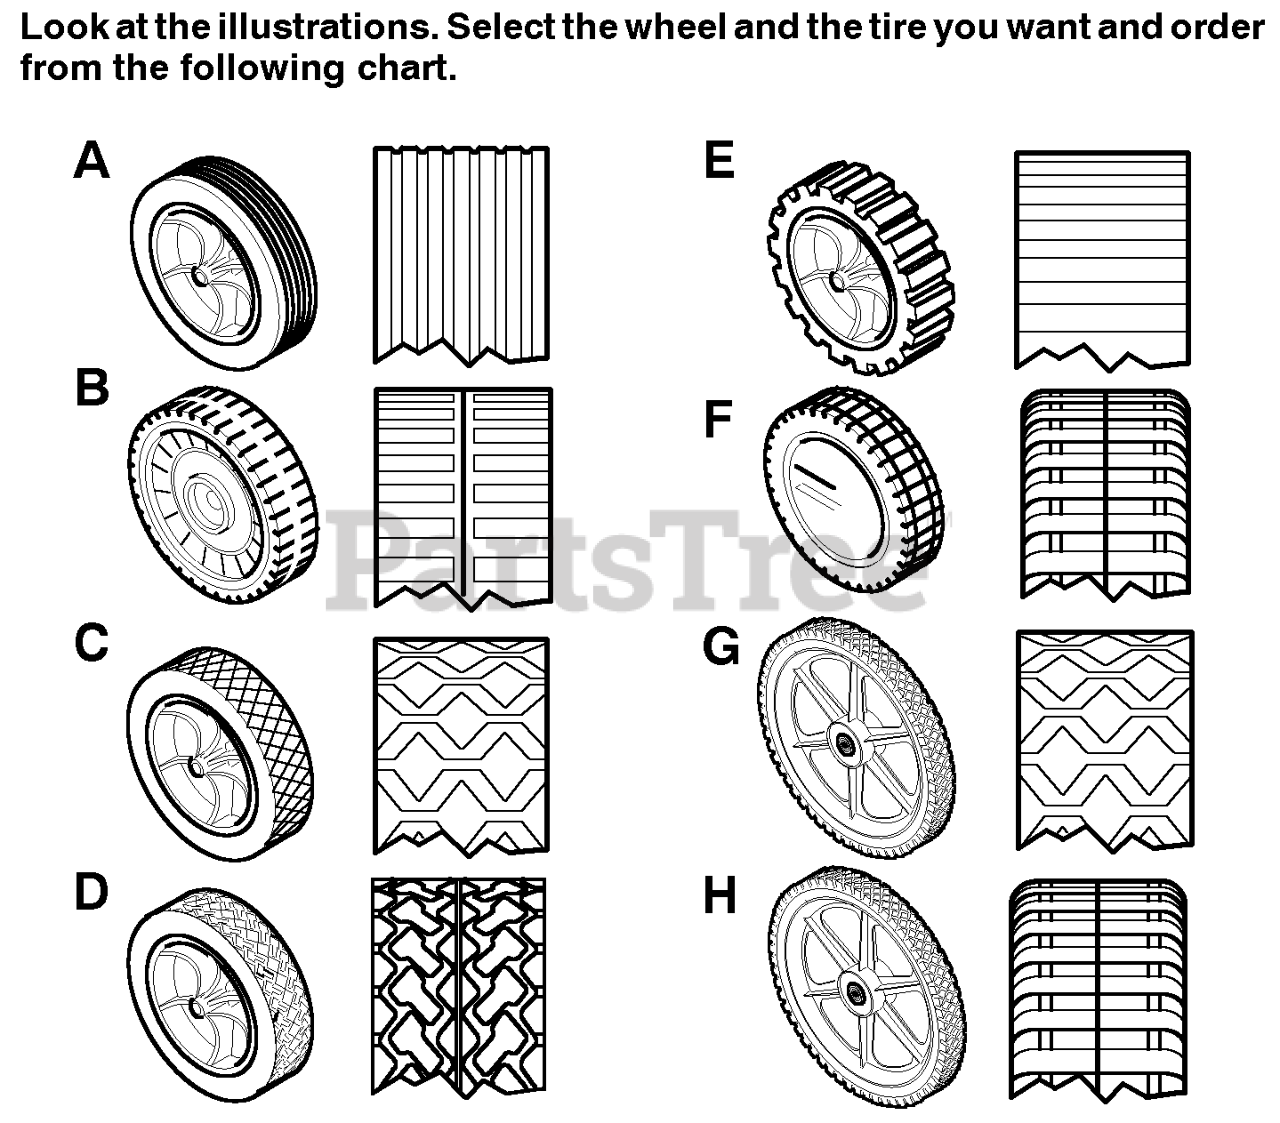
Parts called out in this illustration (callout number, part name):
A	WHEEL & TIRE ASSEMBLY, Light Gray, 8"
A	8-inch Plastic, Dark Gray
A	8-inch Metal, White
B	7-inch Plastic, White
B	7-inch Plastic, Light Gray
B	7-inch Plastic, Dark Gray
C	6-inch Plastic, White
C	7-inch Plastic, White
C	7-inch Plastic, Light Gray
C	7-inch Plastic, Dark Gray
C	8-inch Plastic, White
C	8-inch Plastic, Light Gray
C	8-inch Plastic, Dark Gray
C	8-inch Metal, White
D	7-inch Plastic, White
D	WHEEL & TIRE ASSEMBLY, White, 8"
D	8-inch Plastic, Light Gray
D	8-inch Plastic, Dark Gray
E	WHEEL & TIRE ASSEMBLY, White, 8"
E	8-inch Plastic, Dark Gray
E	8-inch Metal, White
F	WHEEL & TIRE ASSEMBLY, White, 8"
F	8-inch Plastic, Light Gray
F	8-inch Plastic, Dark Gray
F	8-inch Ball Bearing, Light Gray
F	8-inch Ball Bearing, Dark Gray
G	14-inch, White
G	14-inch, Light Gray
G	14-inch, Dark Gray
G	WHEEL & TIRE ASSEMBLY, White, 14"
G	14-in, Ball Bearing, Light Gray
G	14-in, Ball Bearing, Dark Gray
H	14-inch, White
H	14-inch, Light Gray
H	14-inch, Dark Gray
H	WHEEL & TIRE ASSEMBLY, Ball Bearing, 14"
H	14-in, Ball Bearing, Light Gray
H	14-in, Ball Bearing, Dark Gray
